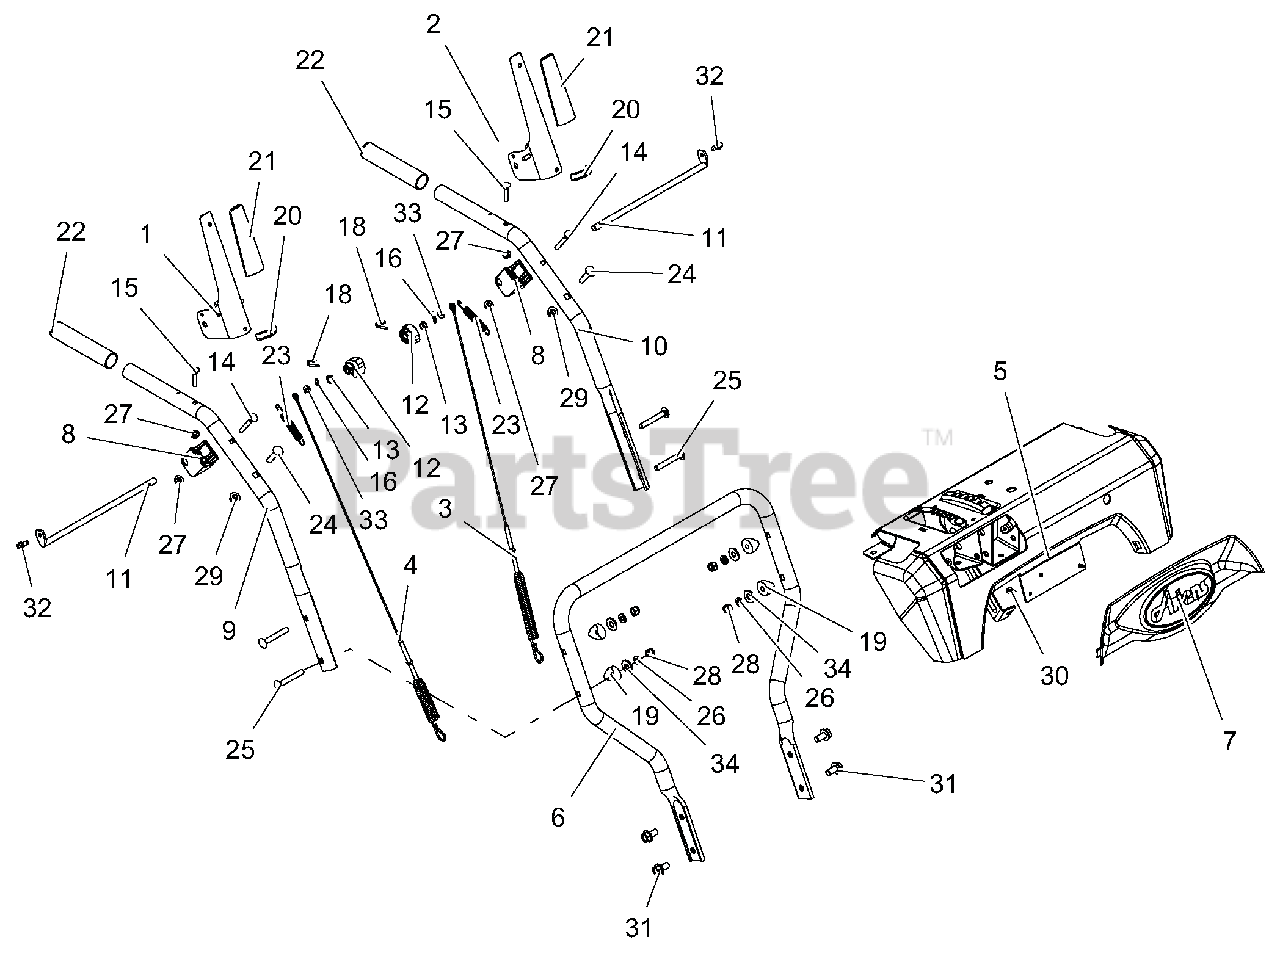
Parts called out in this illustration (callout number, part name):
1	LEVER, CLUTCH-RH
2	LEVER, CLUTCH-LH
3	CABLE, UPPER TRACTION
4	CABLE, AUGER (DELUXE & PRO)
5	CONTROL PANEL W/DECAL ID,AT
6	HANDLEBAR, LOWER - DELUXE
7	DASH BEZEL, ARIENS LOGO - PRO
8	BLOCK, CLUTCH PADDLE
9	HANDLEBAR, UPPER - RH
10	HANDLEBAR, UPPER - LH
11	ROD, PADDLE MOUNT - PRO
12	CAM, INTERLOCK
13	BUSHING, POLYLINER-.38 SNAPIN
14	BLT-RDHDXLSQNK .25-20X2.0 G5YZ
15	BLT-RDHDXLSQNK.25-20X1.25 G5ZC
16	PIN-HAIR INT .06X.18X.77
18	PIN, SPRING CLIP
19	SPACER, HANDLEBAR
20	EDGING, CLUTCH PADDLE - 2.00"
21	CLUTCH PADDLE SLEEVE - GRAY
22	HANDLE GRIP
23	SPRING, EXTENSION
24	@BLT-RDHDSQNK .31-18X1.50 G5YZ
25	@BLT-RDHDSQNK .31-18X2.25 G5YZ
26	WSHR-LK .312X.097 HVY YWZC
27	@NUT-LK-CTR-FLG .25-20 YWZC
28	@NUT-LK-NYL .312-18 YWZC
29	@NUT-LK-TOP-FLG .31-18 YWZC
30	SCR-TAP #10X.50 BOSS INDHXHD
31	BLT-SERHFWH .38-16X.75 YWZC
32	SCR-TAP .25-20X.50 HWH TR YWZ
33	@WSHR-FL-STL.281X.62X.065 YWZC
34	@WSHR-FL-STL.38X.875X.083 YWZC
